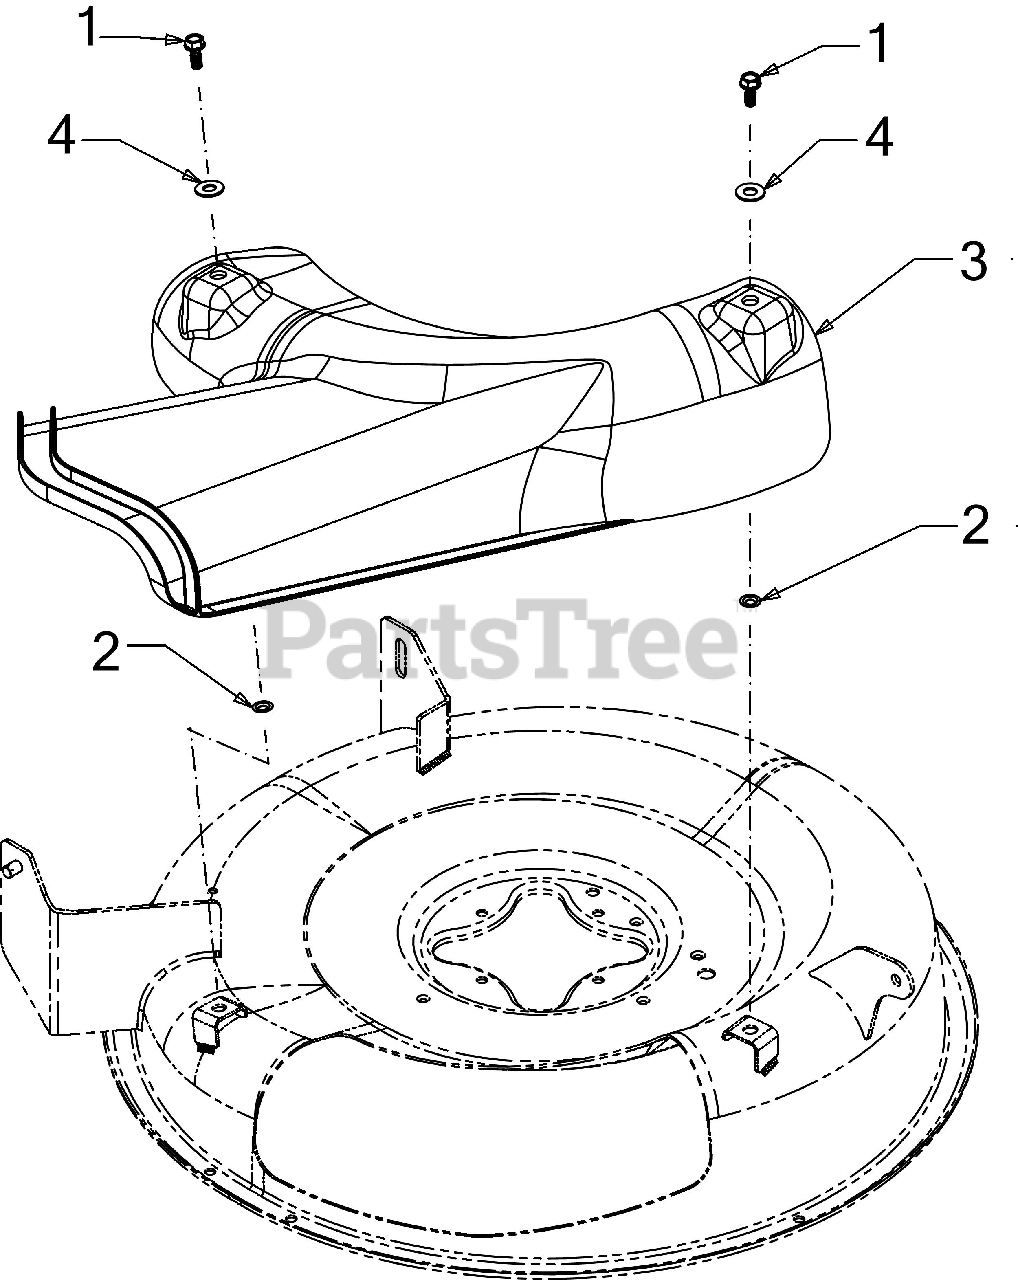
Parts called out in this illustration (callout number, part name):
1	HEX SCREW 5/16-18 x .750
2	PUSH NUT
3	DISCHARGE CHUTE
4	FLAT WASHER
